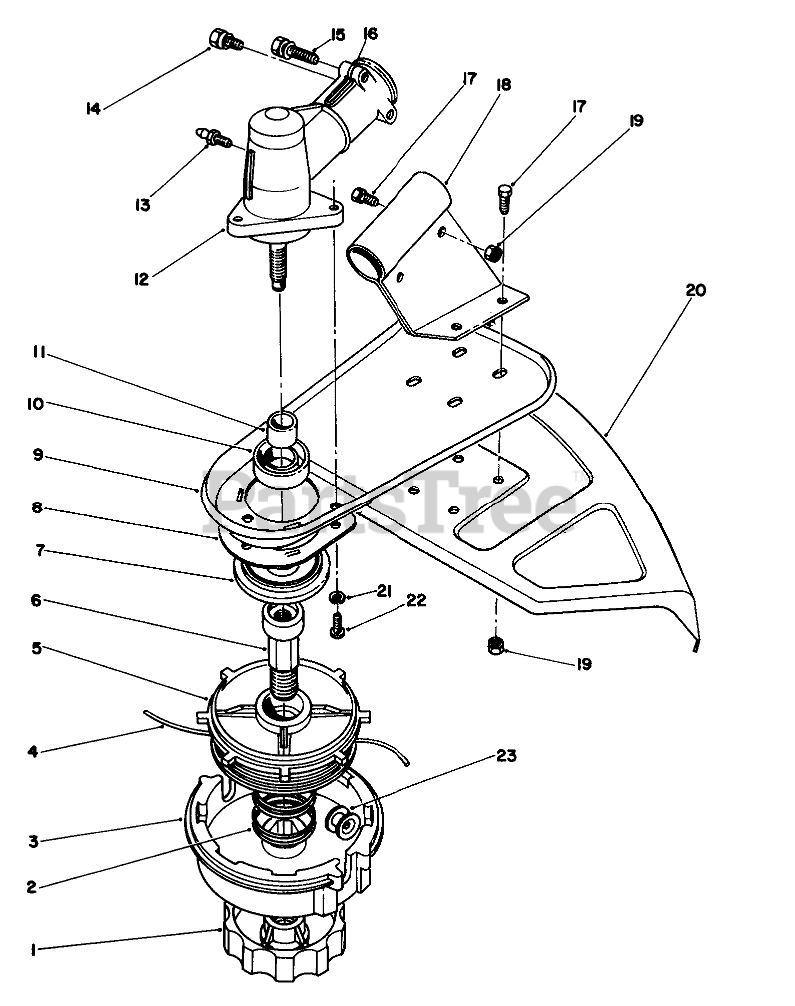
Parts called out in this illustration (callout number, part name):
1	LH KNOB(SERVICE ONLY)
2	SPRING (SERVICE)
3	SPOOL HSG (SERVICE ONLY
4	REPL LINE PKG
5	INNER SPOOL(SERV ONLY)
6	SHAFT (SERVICE ONLY)
7	DUST CAP F/W
8	GRASS WRAP GUARD
9	SHIELD SUPPORT R
10	OIL SEAL
11	SPLINED SLEEVE
12	Gear Box Assembly (Incl. Ref. #10, 11, & 13-16)
14	HHMS SCREW
15	HHMS SCREW
16	WASHER
17	SCREW-SHH
18	SHIELD BRKT
19	NUT-LOCK, NI
20	GRASS SHIELD R
21	LOCKWASHER
22	SCREW
23	EYELET(SERVICE)
